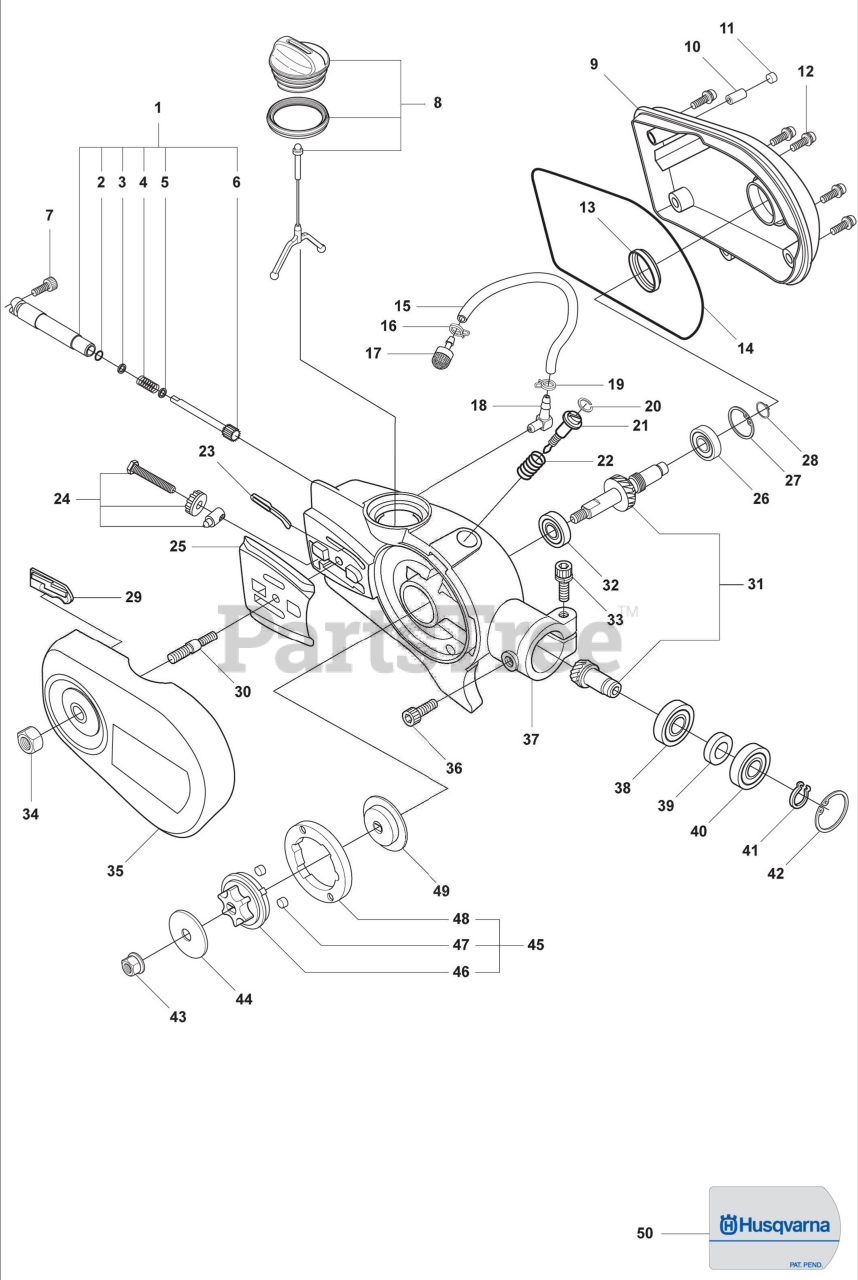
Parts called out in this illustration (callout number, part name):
2	O-Ring, 5.1 X 1.6 NITRILE
3	Washer, 5.1 X 8.5
5	Washer, 5.1 X 8.5
6	Pump Piston
7	Screw, MC6S 5 X 12
8	Oil Tank Cap, Grey
12	Screw, MC6S 5 X 16
17	Oil Plummet
20	Retaining Ring
24	Chain Tensioner
26	Ball Bearing
27	Retaining Ring
29	Sealing Plate
32	Ball Bearing
33	Screw, MC6S 5 X 25
34	Hex Nut
36	Screw, MC6S 5 X 12
38	Ball Bearing
39	SPACER SLEEVE
40	Ball Bearing
41	Retaining Ring
42	Retaining Ring
43	Hex Flange Nut
44	Fender Washer
45	Sprocket Kit
47	Vibration Absorber
